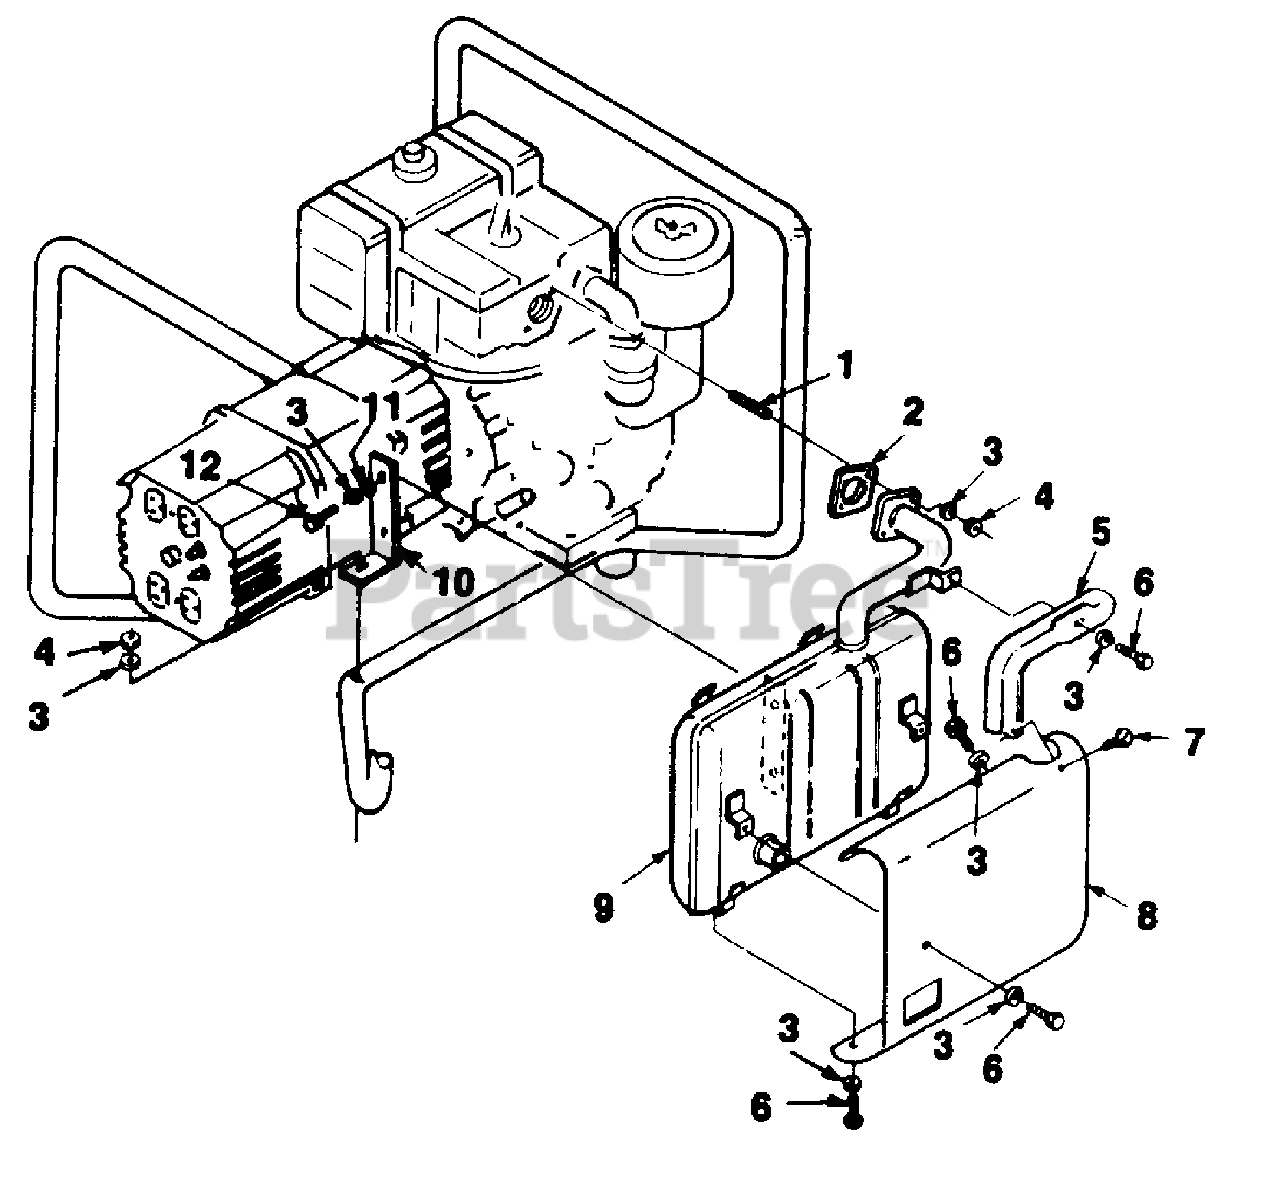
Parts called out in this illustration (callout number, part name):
1	STUD
2	GASKET- Muffler
3	WASHER- Lock (1/4")
4	NUT- (1/4-28)
5	SHIELD- Muffler
6	BOLT- (1/4-20 x 1")
7	SCREW- (8-18 x 3/8")
8	SHIELD- Muffler
9	MUFFLER
10	BRACKET- Support
11	WASHER- Flat
12	BOLT- (1/4-20 x 1/2")
